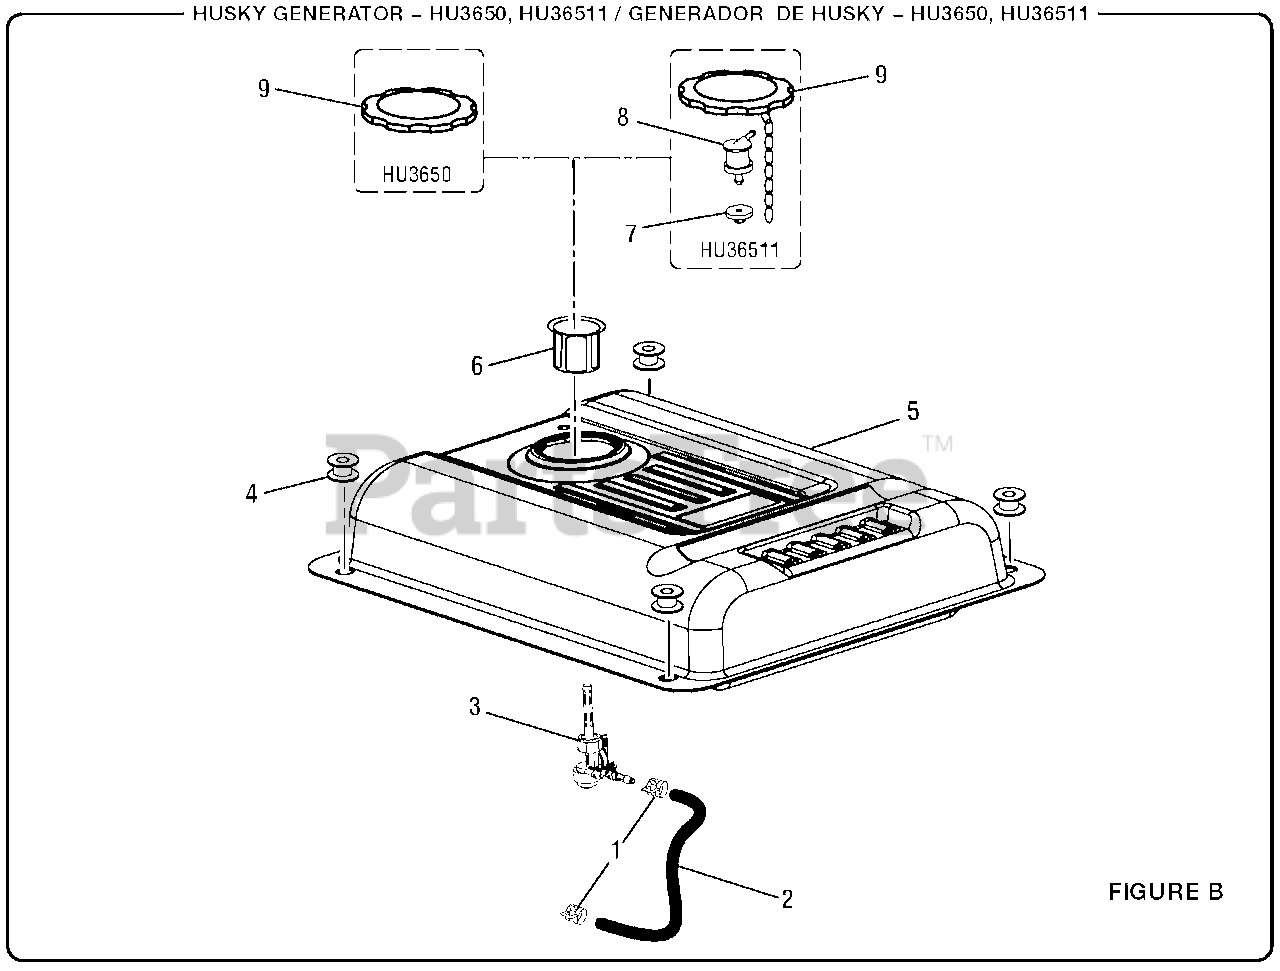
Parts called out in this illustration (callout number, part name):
1	Fuel Line Clamp
2	Fuel Line
3	Fuel Shut Off Valve
4	Bushing w/Insert
5	Fuel Tank (HU3650)
6	Strainer Basket
7	Check Valve Bushing (HU36511)
8	Check Valve (HU36511)
9	Fuel Cap (HU3650)
